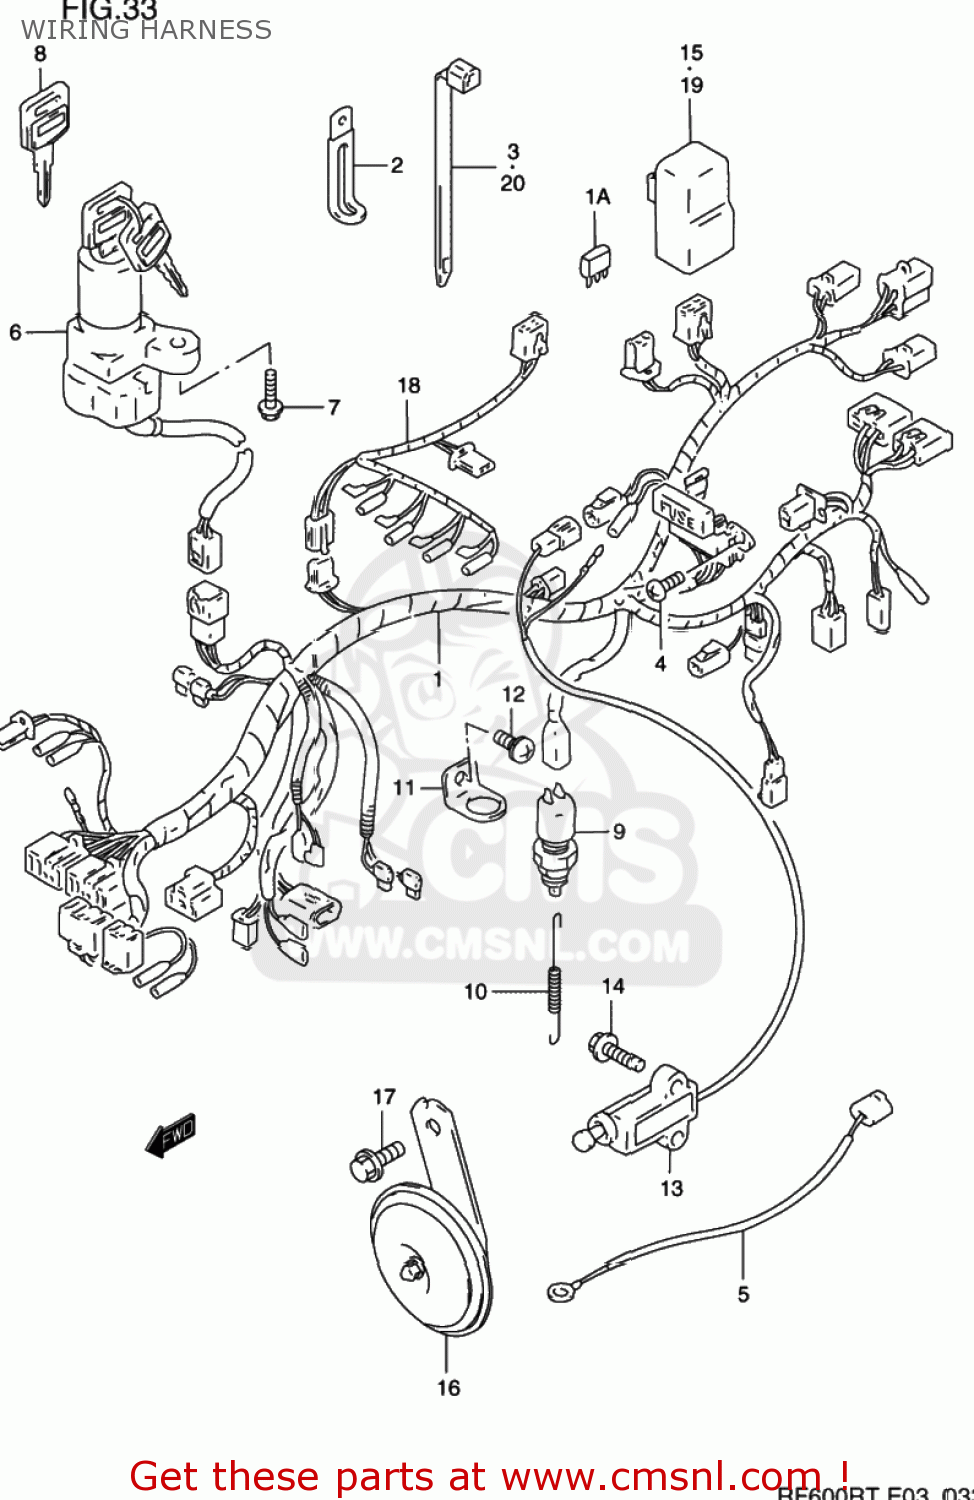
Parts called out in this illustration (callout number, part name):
1	HARNESS,WIRING
1A	DIODE(STANLEY DE8804)
2	CLAMP(L:45)
3	CLAMP L:165
4	SCREW 6X12
5	WIRE
6	LOCK ASSEMBLY,STEERING
7	SCREW(6X18)
8	KEY,BLANK
9	SWITCH ASSY,STOP LAMP
10	SPRING
11	BRACKET,STOP LAMP SWITCH
12	SCREW
13	SWITCH ASSY,SIDE STAND
14	BOLT
15	RELAY ASSY
16	HORN ASSEMBLY,LOW PITCH
17	BOLT
18	WIRE,CARBURETOR HEATER LEAD
19	RELAY ASSY
20	CLAMP(L:125)
